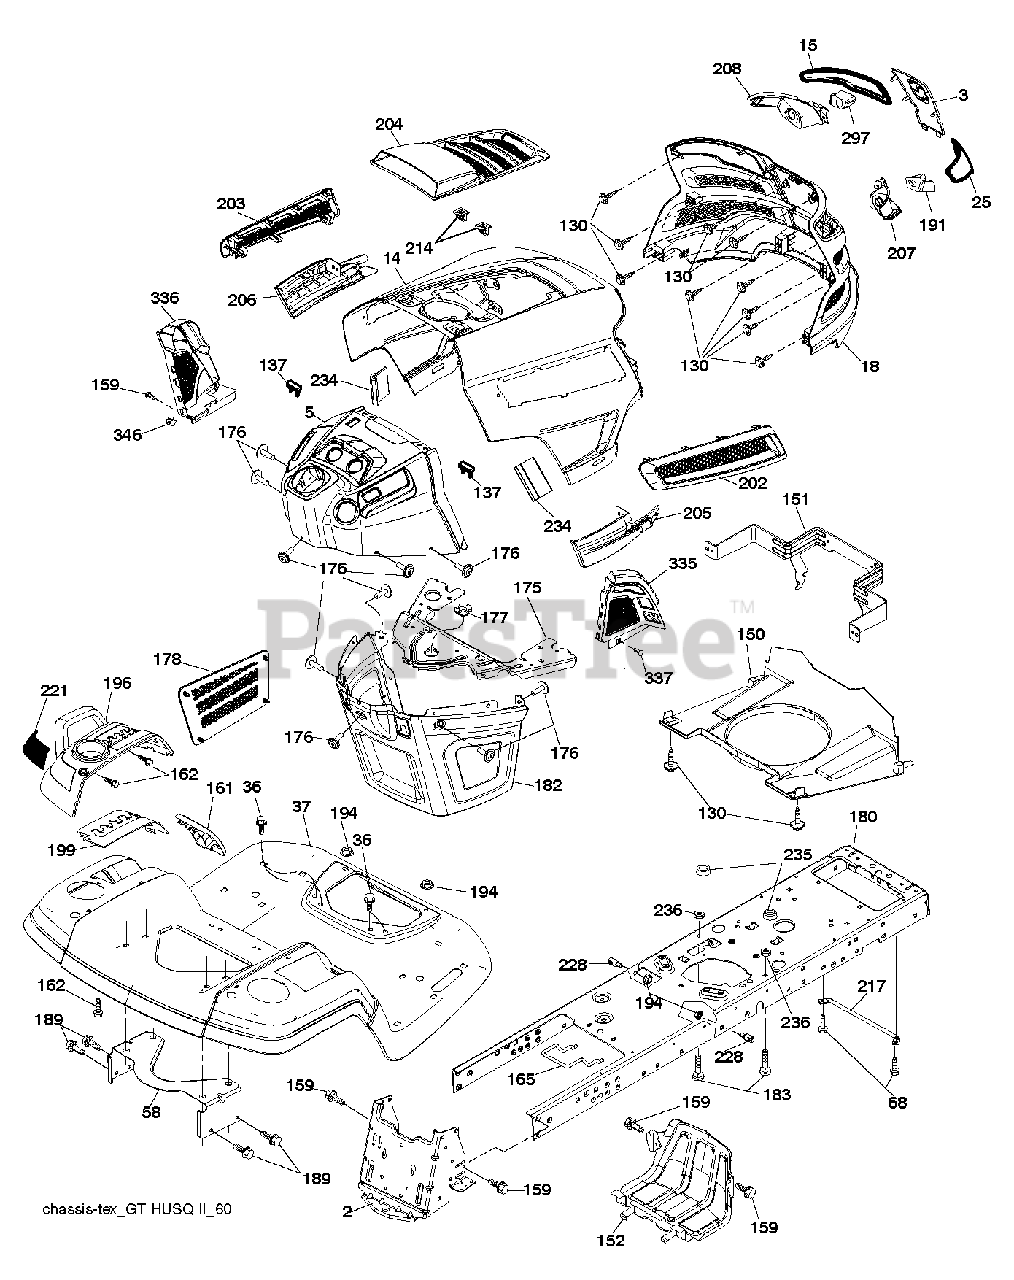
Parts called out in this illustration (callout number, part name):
2	DRAWBAR.STGT
3	APPLIQUE.SUBASM.GT.HUSQ.II
5	DASH.UPP.GT2.DR.PTO.ELEC.CHOKE
14	HOOD.ASM.HUSQVARNA.GT.TEX.ORAN
15	LENS.HEADLIGHT.LH.GTII.2011
18	GRILLE.SUBASM.GT.HUSQ.II
25	LENS.HEADLIGHT.RH.GTII.2011
36	SCREW 5/16"
37	FENDER.PNT.TX.GT.CH/FW/DL.HUSQ
58	BRKT.SUPPORT.FNDR/TANK
68	SCREW LT
130	SCREW.#10 X 0.750.BOS
137	BUMPER DASH
150	AIR.DUCT.GTV.BLACK
151	BRACKET.PIVOT.HOOD.GT.HUSQ.II
152	SHIELD.BROWNING.PNT.GT.V2
159	SCREW, 3/8-16X3/4
161	CONSOLE.WINDOW.FUEL.HUSQ.GT
162	SCREW.HI-LO.CONSOLE
165	SUPPORT.TANK.REAR.B/TE
175	PLATE.CROSSMEMBER.HUSQ
176	SCREW.#10-24X5/8.RN.QU
177	BUSHING, STEERING
178	CARGO.ASM.NET.TXGT.W/C
180	CHASSIS.STAMPING.LT/GT
182	DASH.LOWER.COMMON.12V.ADAPTOR
183	BOLT.5/16-18X1-1/4 FULL THD
189	SCREW
191	INSERT.REFLECTIVE.RH.HUSQ.GTII
194	NUT LOCK HEX FLANGE 5/16-18
196	CONSOLE.ASM.DECKLIFT.HUSQGT.DL
199	PLATE.DECK.LIFT.HUSQVARNA.GT
202	VENT.SIDE.RH.GT.HUSQ.II.
203	VENT.SIDE.LH.GT.HUSQ.II.498
204	VENT.TOP.HUSQ.GT2
205	SIDE.TRIM.RH.GT.HUSQ.II
206	SIDE.TRIM.LH.GT.HUSQ.II.GRAY
207	BEZEL LIGHT.RH.GT.II.MYLAR
208	BEZEL LIGHT.LH.GT.II.MYLAR
214	CLIP.RETAINER.TINNER.
217	ROD.PIVOT.HOOD
221	REFLECTOR.LH.TEX GT HU
228	STUD.FASTNER.W/ANTI-ROTATE
234	BUMPER.HOOD.TEX.HUSQVARNA
235	SPACER FENDER
236	NUT.CENTERLOCK.5/16-
297	INSERT.REFLECTIVE.LH.HUSQ.GTII
335	COVER.RH.CLOSE.OUT.BLACK
336	COVER-LH.LOWER.DASH.GT2.BLACK
337	CLIP.XMAS.TREE.ITW.2622-00
346	CLIP,INSULATOR
